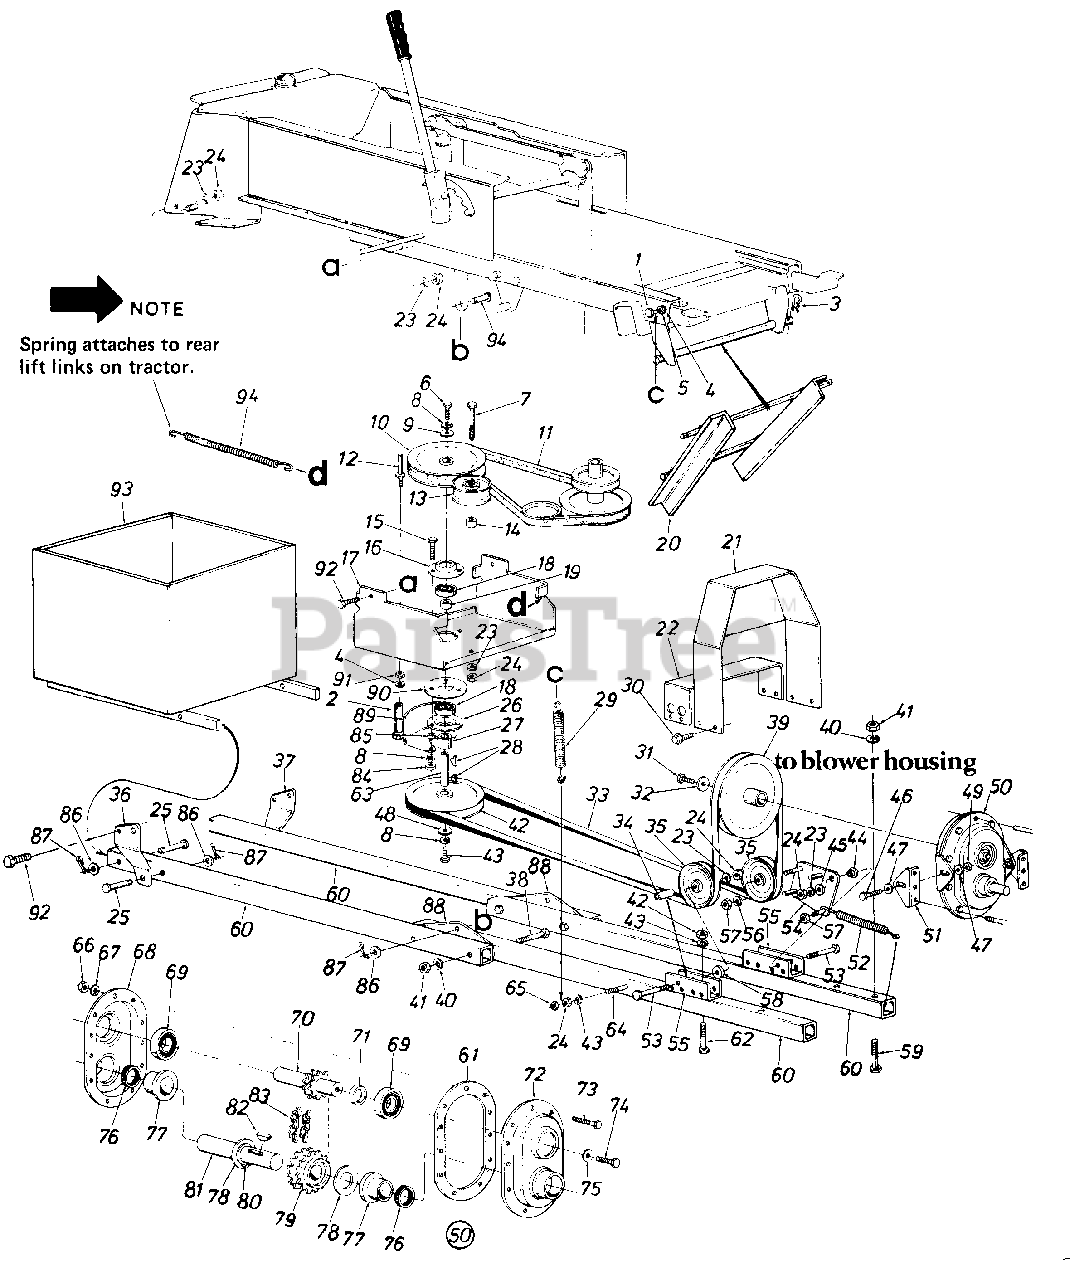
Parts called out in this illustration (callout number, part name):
1	Hex Bolt 1/4-28 x 1.50"
2	Clevis Pin Special 3/8" Dia. x 2.62" Lg.
3	Inter. Cotter Pin 1/2" Dia.
4	L.-Wash. 1/4" I.D.
5	Hex Nut 1/4-28 Thd.
6	Hex Bolt 3/8-24 x 1.0" L.
7	Hex Bolt 3/8-16 x 2.25" Lg.
8	L.-Wash. 3/8" I.D.
9	L.-Wash. .39" I.D. x 1.25" O.D.
10	5/8" "V"-Pulley .790" I.D. x 6.50 O.D
11	"V" Belt 1/2' x 52.0" Lg.
12	Belt Guard Pin 1/4" Dia. x 1.68" Lg.
13	Fl.-Idler w/flanges3.75" O.D.
14	Spacer .385" I.D. x .630" O.D. x.760" Lg.
15	Hex Bolt 5/16-24 x 1.50" Lg.
16	Open Brg. Housing 1.85" I.D.
19	Spacer 1.0" O.D. x .790" I.D. x.350" Lg.
20	Guide Bracket Ass'y.
21	Belt Cover Ass'y.
22	Belt Cover Brkt.
23	L.-Wash. 3/8" I.D.
24	Hex Nut 3/8-16 Thd.
25	Clevis Pin .50" Dia. x 2.75" Lg.
26	Bearing Housing 1.85" I.D.
27	Spacer .80" I.D. x 1.00" O.D. x.125" Lg.
28	Hi-Pro-Key 3/16 x 5/8"
29	Extension Spring 1.00" O.D. x 6.44" Lg.
30	Hex Wash. HD. Sf. Tap Scr. 5/16-24x.50" Lg.
31	Hex L.-Bolt 3/8-24 x 1.00" Lg.
32	Bell.-Wash. .400"I.D. x 1.25" O.D.
33	"V"-Belt 1/2" A x 112.0" Lg.
34	Spacer .39" I.D. x .62" O.D. x 1.74" Lg.
35	5/8" "V"-Belt Idler 4.00" O.D.
39	5/8" "V"-Pulley 1.00" I.D. x 7.50" O.D.
40	L.-Wash. 1/2" I.D.
41	Hex Nut 1/2-13 Thd.
42	5/8" "V"-Pullev .79"I.D. x6.5"
43	Hex Bolt 3/8-24 x 1.0" Lg.
44	Shoulder Spacer .625" I.D.
45	Fl.-Wash. .400" I.D. x 1.25" O.D
46	Hex Bolt 5/16-18 x .75" Lg.
47	Bell.-Wash. .345" I.D. x .88" O.D.
48	Fl.-Wash. .39" I.D. x 1.25" O.D.
49	Hex Nut 5/16-18 Thd.
50	Comp. Chain Gear Box Ass'y.
51	Gear Box Support Brkt.
52	Extension Spring .87" Dia. x 6.00" Lg.
53	Hex Bolt 3/8-16 x 3.0" Lg. (Grade 8)
56	Fl.-Wash. .385"I.D. x .87 O.D.
57	Hex Ins. L.-Nut 3/8-24 Thd.
58	Fl.-Wash. .400" I.D. x 1.25" O.D. x .157 Thk.
59	Hex Bolt 1/2-13 x 3.00" Lg.
62	Hex Bolt 3/8-15 x 3.0" Lg. (Grade 8)
63	Shaft-.787" Dia. x 3.81" Lg.
64	Hex Bolt 3/8-16 x 3.25" Lg.
65	Hex Cent. L.-Jam Nut 3/8-16 Thd.
66	Hex Nut 1/4-28 Thd.
67	Spr.-Wash. .270" I.D. x.57" O.D
68	Gear Hsg. Half-L.H.
69	Ball Brq. 1.00"I.D. x 2.00" O.D.
70	11-2x.5 Pitch-Sprkit.ShaftAss'y.
71	Spacer 1.00" I.D. x 1.18" O.D. x .440 Lg.
72	Gear Hsg. Half-R.H.
73	Hex Bolt 1/4-28 x 1.00" Lg. (Grade 5)
74	Hex L.-Bolt 3/8-24 x 1.00" Lg.
75	Bell.-Wash. .400" I.D. x 1.25" O.D.
76	Oil Seal 1.25" x 1.75" O.D.
77	Flange Brg. 1.252" I.D.
78	Fl.-Wash. 1.25" I.D. x 2.00" O.D
79	DBL Sprkt. 19-2 Teeth x .500" Pitch
80	Snap Ring for 1.25" Dia. Shaft
81	Gear Shaft 1.25" Dia. x 6.0" Lg.
82	#A Hi-Pro Key 1/4 x 7/8" Dia.
83	40-2 Chain 1/2" Pitch x 25 Links
84	Hex Nut 5/16-24 Thd.
85	Spacer .380" I.D. x .625" O.D. x.227" Lg.
86	Fl.-Wash. .510" I.D. x 1.0" O.D
87	Inter. Cot.-Pin 1/2" Dia.
91	Hex Nut 1/4-20 Thd.
92	Hex Bolt 3/8-16 x 1.0" Lg.-Gr. 5
